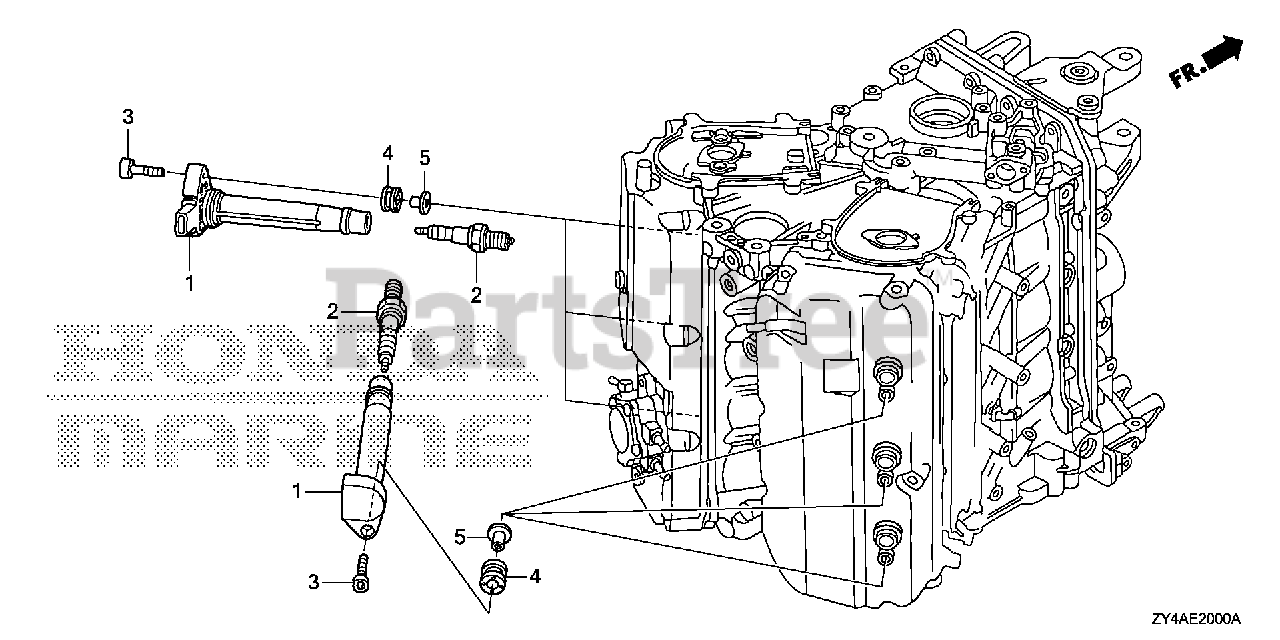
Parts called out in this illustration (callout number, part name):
1	COIL, PLUG HOLE
2	SPARK PLUG (IZFR6F11) (NGK)
2	SPARK PLUG (VKJ20RZ-M11) (DENSO)
3	BOLT, SOCKET (6X25)
